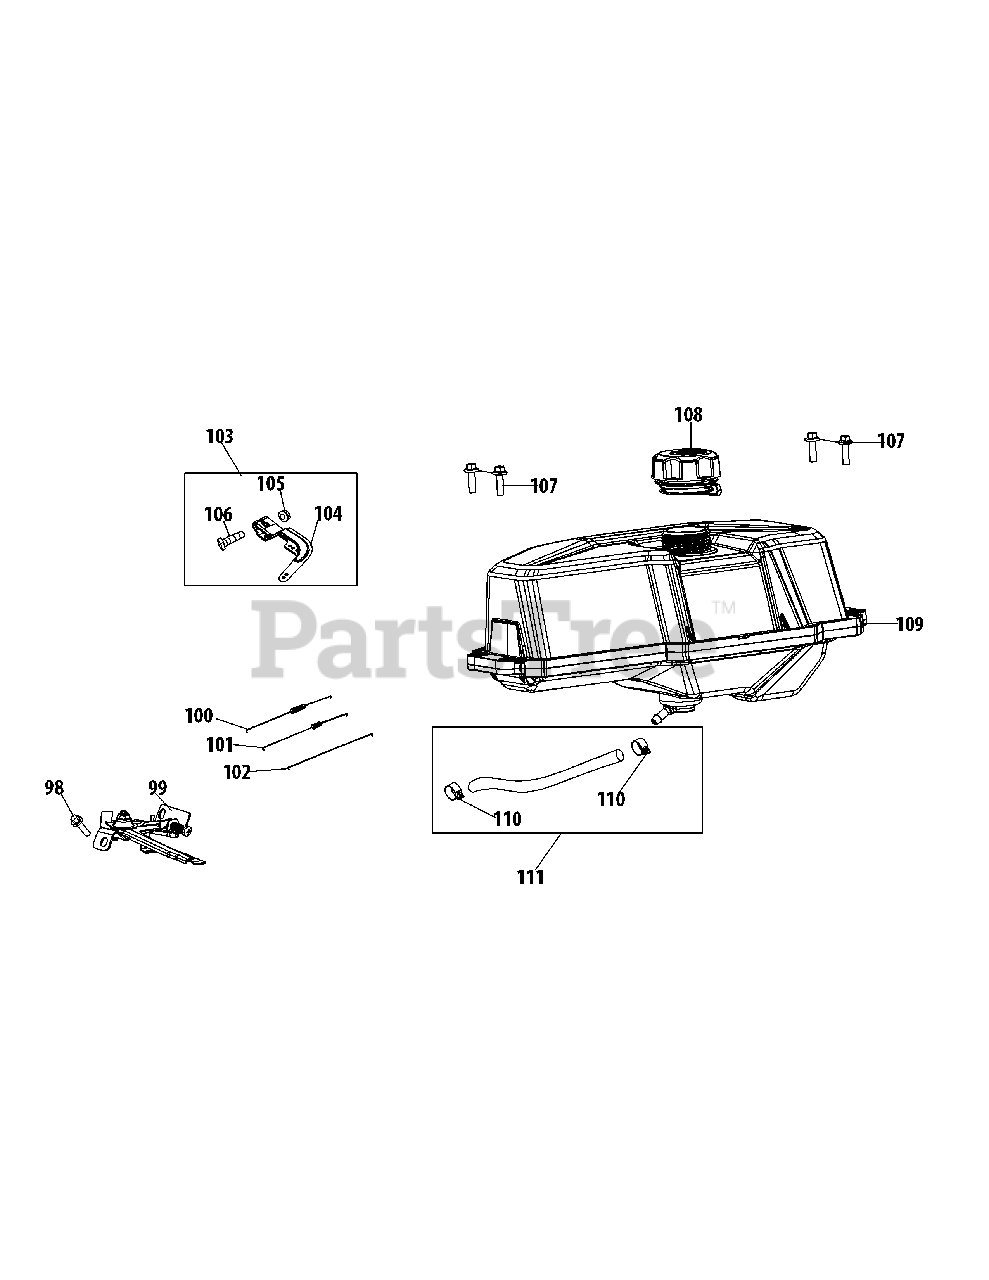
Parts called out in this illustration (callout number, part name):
98	Flange Bolt M6×12
99	Governor Gear Bracket Assy
100	Governor Spring
101	Idle Spring
102	Rod Governor
103	Governor Lever
104	Governor Lever
105	Flange Nut M6
106	Bolt M6×21
107	Bolt M6×22
108	Fuel Cap
109	Fuel Tank
110	Clamp, Fuel Hose
111	Fuel Hose 6.3×12.5×140
